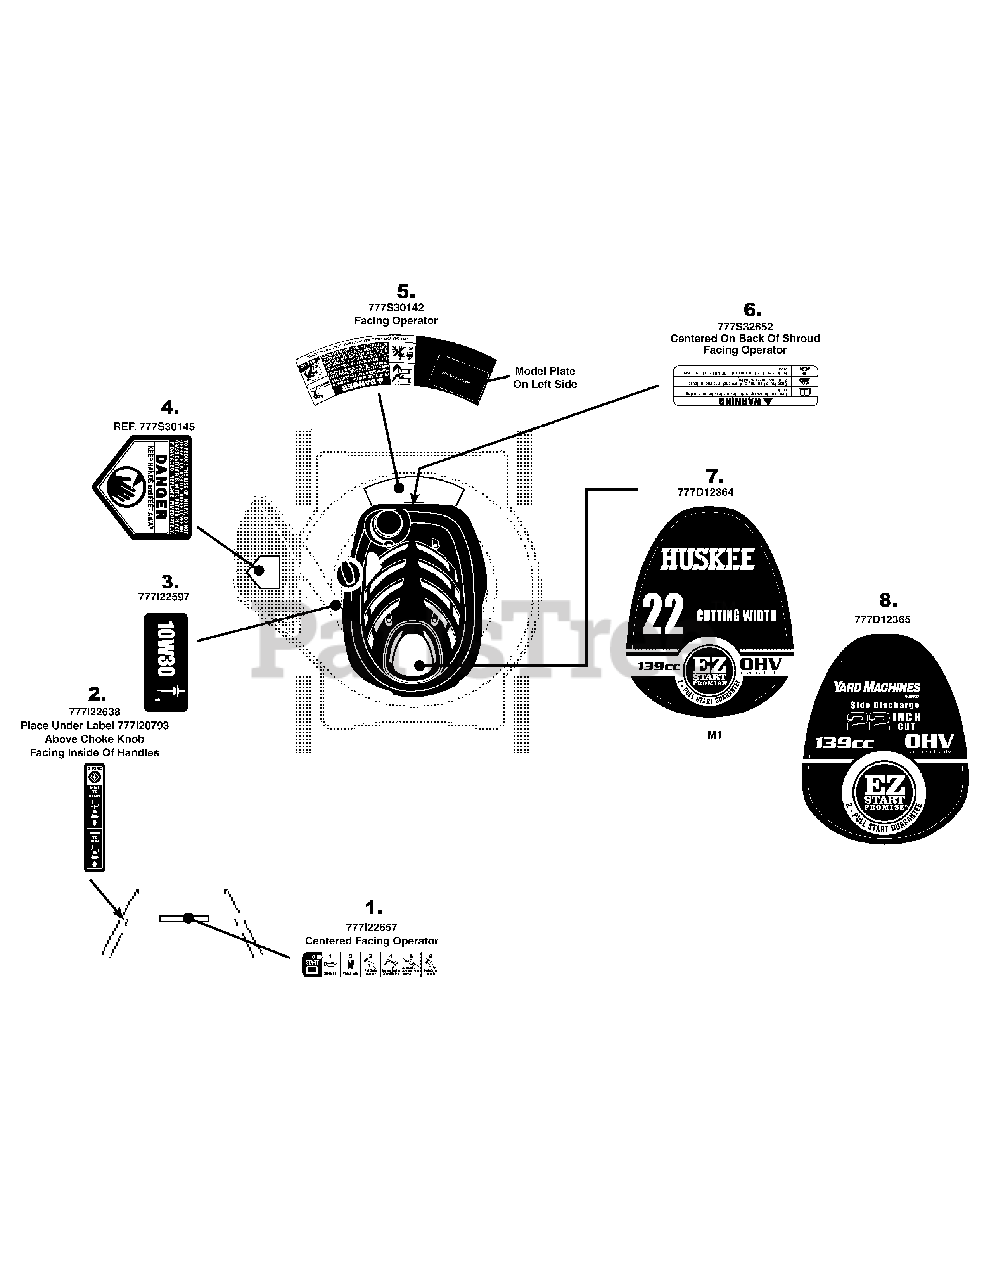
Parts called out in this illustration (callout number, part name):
1	LABEL-MOWER HANDLE
2	LABEL-MOWER HANDLE:CHOKE START/RUN
3	LABEL:MOWER SHROUD
4	LABEL
5	LABEL-DANGER CURVE
6	LABEL:MOWER:ENGINE SHROUD
7	LABEL-MOWER SHROUD HUSKEE
8	LABEL-MOWER SHROUD YARD MACH 22"
